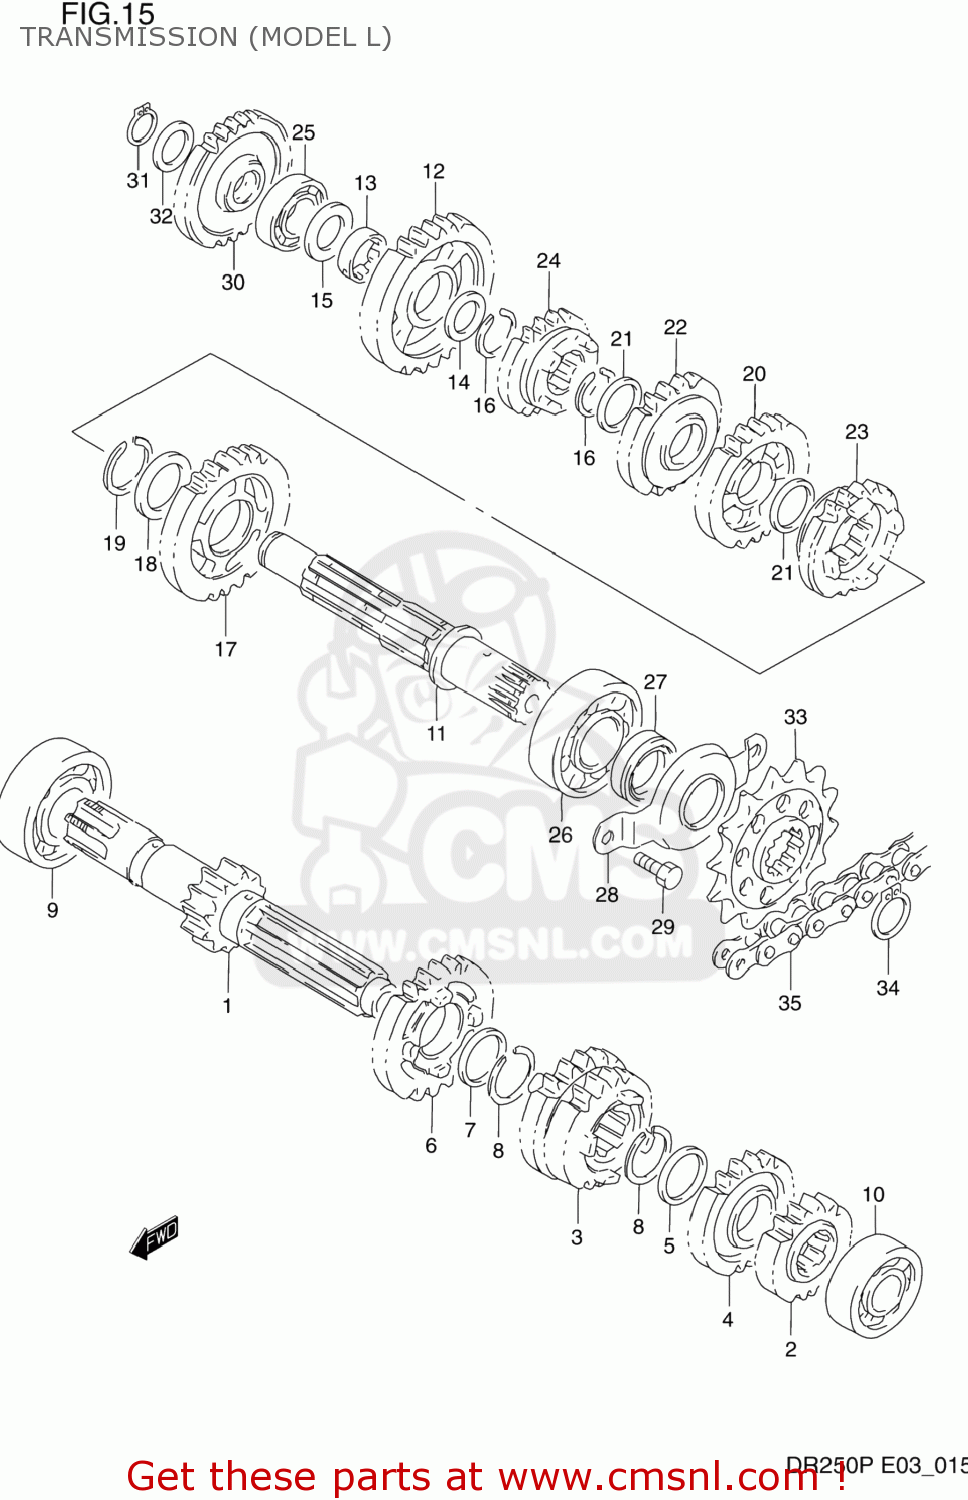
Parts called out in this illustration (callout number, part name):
1	SHAFT,COUNTER
2	GEAR,SECOND DRIVE (NT:15)
3	GEAR,3RD & 4TH DRIVE(NT:18/18)
4	GEAR,5TH DRIVE(NT:21)
5	WASHER
6	GEAR COMP,SIXTH DRIVE
7	SHIM
8	CIRCLIP
9	BEARING
10	BEARING
11	SHAFT COMP,DRIVE
12	GEAR,FIRST DRIVEN (NT:29)
13	BUSH,1ST DRIVEN GEAR
14	WASHER
15	WASHER,THRUST
16	CIRCLIP
17	GEAR,2ND DRIVEN(NT:26)
18	WASHER
19	CIRCLIP
20	GEAR,THIRD DRIVEN
21	SHIM
22	GEAR,4TH DRIVEN(NT:20)
23	GEAR,FIFTH DRIVEN (NT:20)
24	GEAR,SIXTH DRIVEN
25	BEARING(17X42X12)
26	BEARING(22X56X16)
27	SEAL,OIL(22X34X7)
28	RETAINER,DRIVE SHAFT OIL SEAL
29	BOLT
30	GEAR,KICK STARTER IDLE
31	CIRCLIP
32	WASHER,THRUST
33	SPROCKET,ENGINE
34	CIRCLIP
35	CHAIN ASSEMBLY,DRIVE RK520
